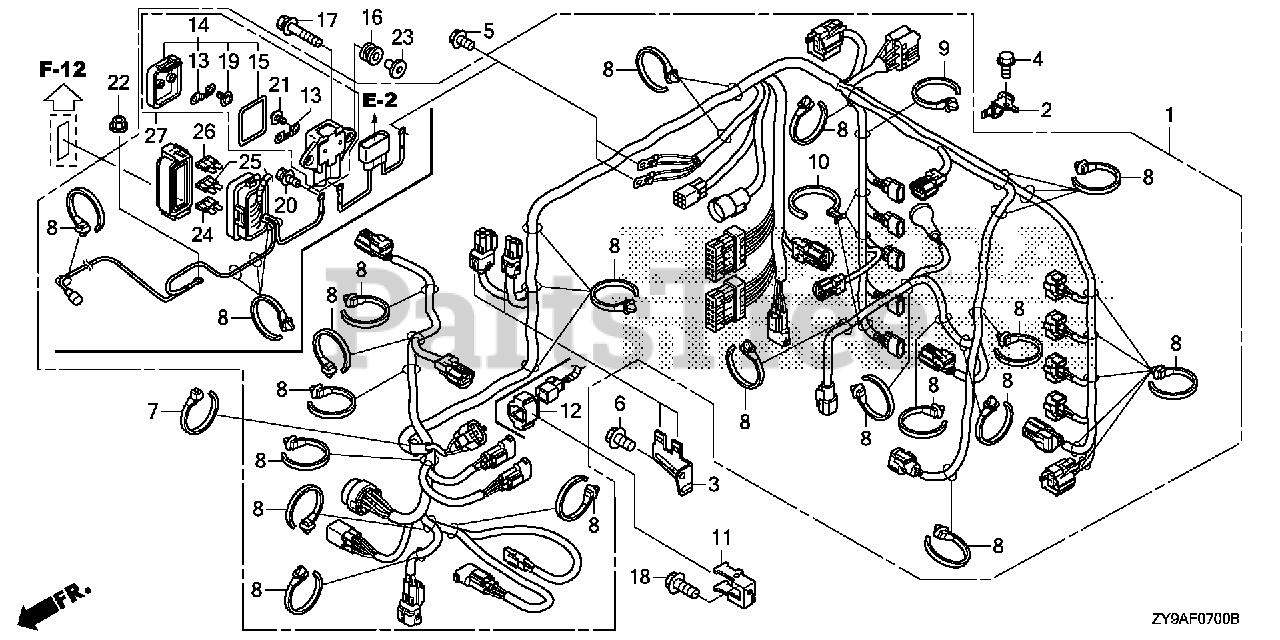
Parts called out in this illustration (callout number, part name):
1	WIRE HARNESS ASSY., MAIN
2	BRACKET A, CONNECTOR
3	BRACKET C, CONNECTOR
4	BOLT, FLANGE (6X14) (CT200)
5	BOLT, FLANGE (6X12)
6	BOLT, FLANGE (6X10)
7	BAND, WIRE HARNESS
8	CLIP, HARNESS BAND (145MM) (BLACK)
9	CLIP, HARNESS BAND (151MM) (BROWN)
10	STRAP, HARNESS (30) (107.5MM) (BLACK)
11	BRACKET, CONNECTOR
12	SUSPENSION, CONNECTOR
13	FUSE (70A)
14	COVER ASSY., FUSE (70A)
15	GASKET, FUSE BOX COVER
16	GROMMET, RELAY
17	BOLT-WASHER (6X27) (CT200)
18	BOLT, FLANGE (6X14) (CT200)
19	SCREW-WASHER (3X7)
20	BOLT-WASHER (5X9)
21	SCREW-WASHER (5X10)
22	NUT-WASHER (8MM)
23	COLLAR, MODULE IGNITION CONTROL CASE (CDI)
24	FUSE, MINI (10A)
25	FUSE, MINI (15A)
26	FUSE, MINI (30A)
27	BOX ASSY., FUSE (70A)
